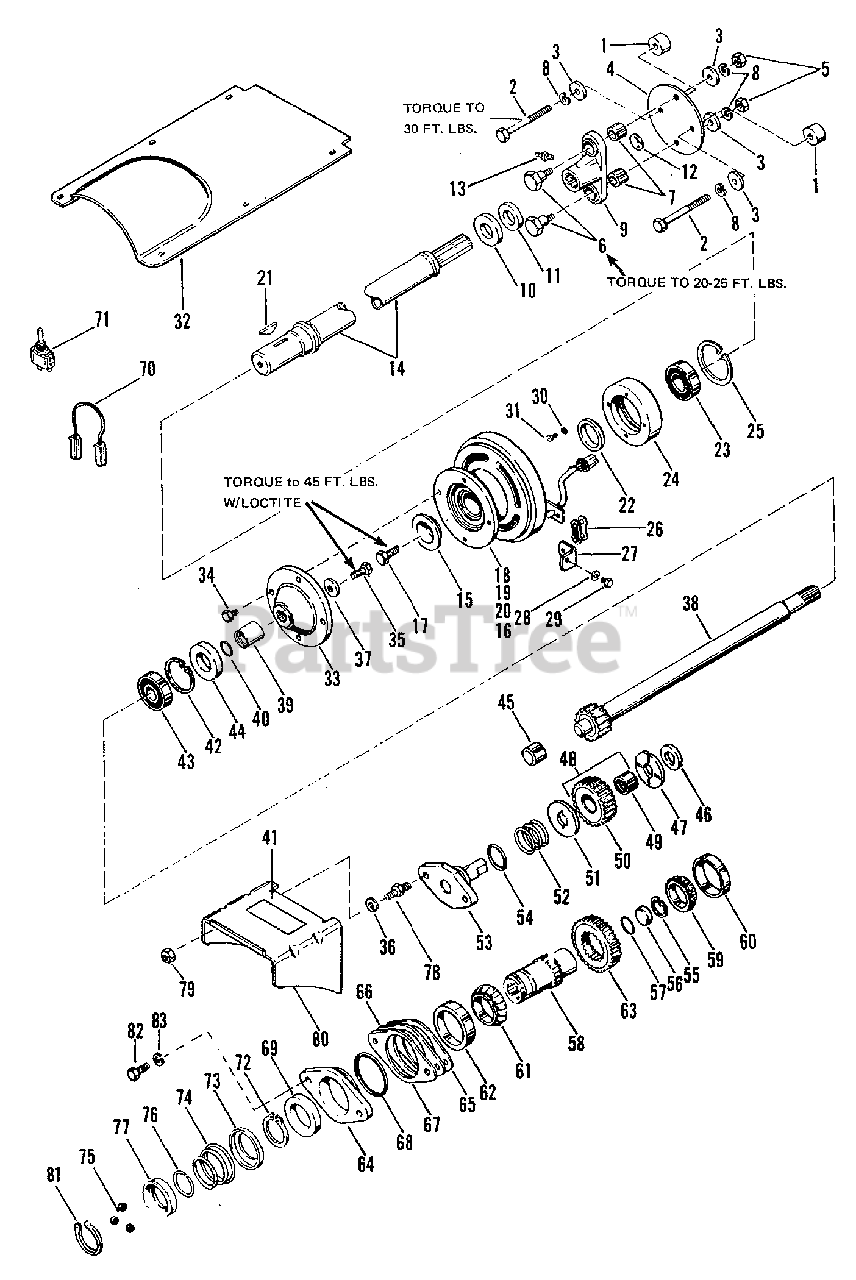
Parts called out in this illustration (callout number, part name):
2	CAPSCREW, Hex, 3/8"-16 x 3-1/2"
3	WASHER, Special
5	NUT, Hex, Jam, 3/8"-16
6	BOLT, Shoulder
8	LOCKWASHER, 3/8"
11	WASHER, Felt
12	PLUG, Plastic
13	FITTING, Grease
14	SHAFT ASSEMBLY
17	CAPSCREW, Hex, Whiz Lock, 3/8"-16 x 1-1/4" LG
18	CLUTCH, Electric
19	FIELD ASSEMBLY
20	ROTOR ARMATURE ASSEMBLY
24	RETAINER, Bearing
25	RING, Retaining
26	LINK, Connector
27	BRACKET ASSEMBLY
28	LOCKWSAHER, 1/4"
29	CAPSCREW, Hex, 1/4"-20 x 3/4" Lg
30	LOCKWASHER, No. 10
31	SCREW, Socket Head, No. 10-32 x 1/2" Lg
32	COVER, Top
34	CAPSCREW, Hex, 5/16"-18 x 1" Lg
35	CAPSCREW, Hex, Whiz Lock, 3/8"-16 x 1" Lg
36	LOCKWASHER, 3/8"
37	WASHER, Special
38	P.T.O. SHAFT ASSEMBLY
41	FILM, Safety
42	RING, Retaining
43	BEARING, Ball
44	SEAL, Brake
47	WASHER, Thrust
48	GEAR ASSEMBLY
49	BEARING
51	WASHER, Thrust
53	CAP ASSEMBLY
54	RING, "O"
55	RING, Retaining
57	RING, "O"
58	SHAFT, Drive
59	CONE, Bearing
60	CUP, Bearing
61	CONE, Bearing
62	CUP, Bearing
65	SHIM, .002
66	SHIM, .010
67	SHIM, .003
70	WIRE, Jumper
71	SWITCH, Electric
72	RING, Retaining
76	RETAINER, Spring
79	NUT, Full Hex, 3/8"-16
81	RING, Retaining
82	CAPSCREW, Hex, 3/8"-16 x 1" Lg.
83	LOCKWASHER, 3/8"
